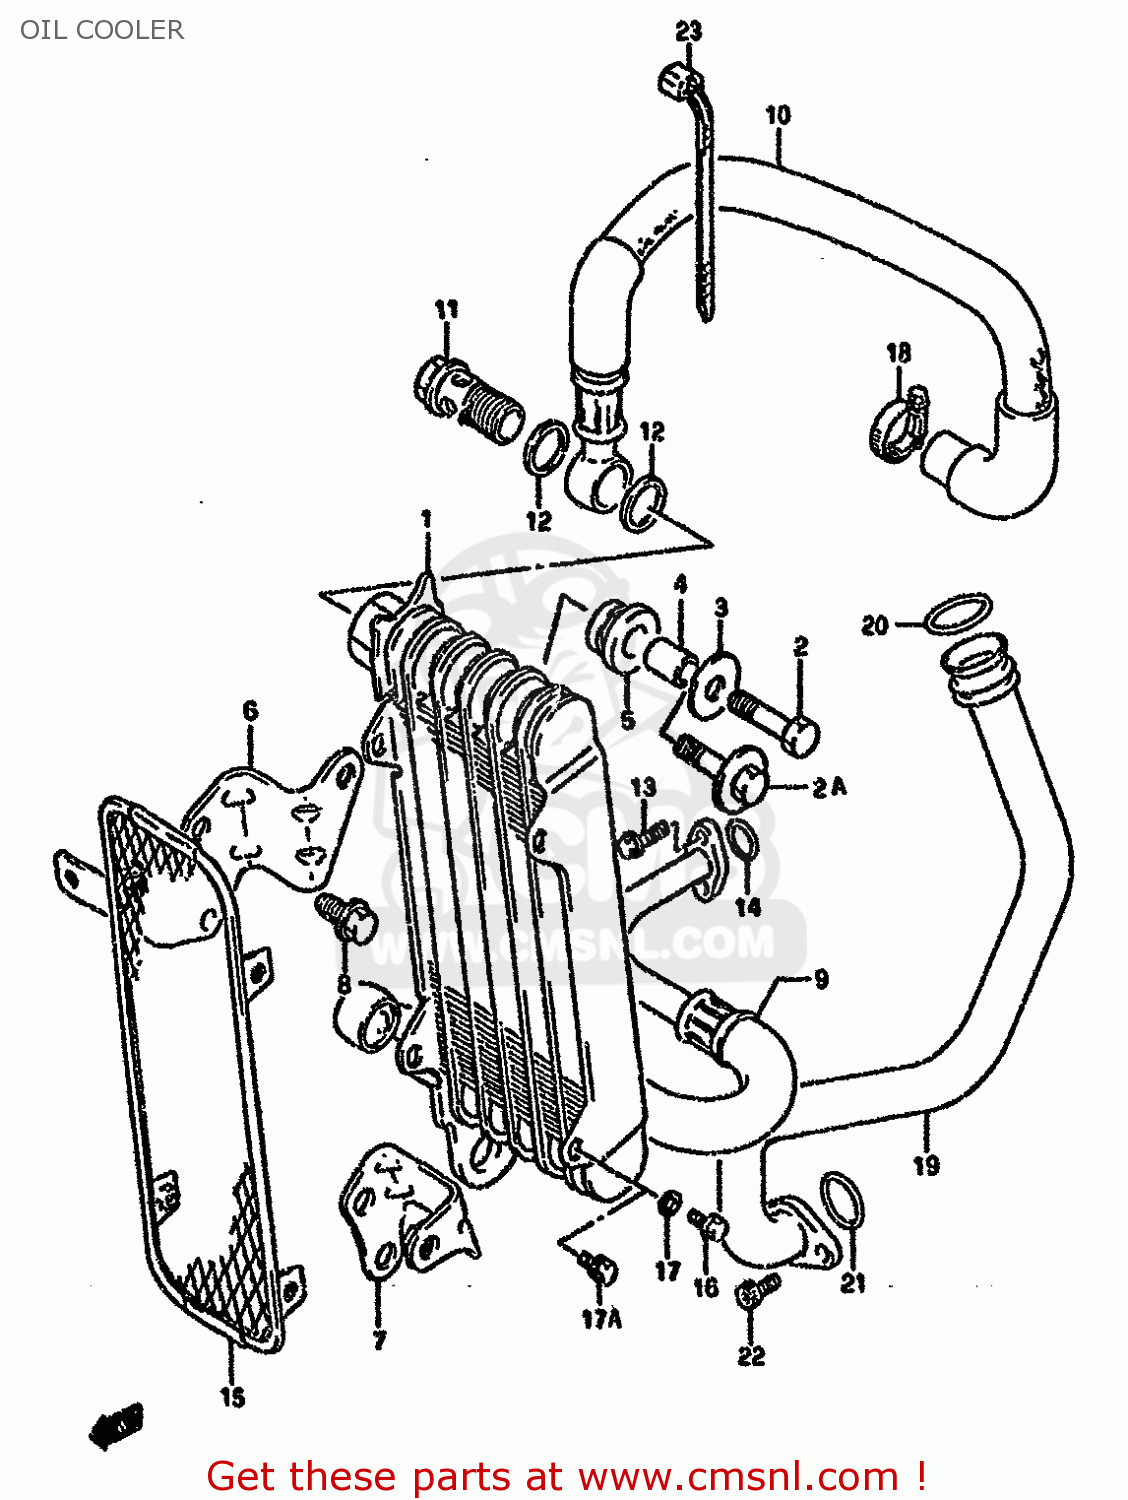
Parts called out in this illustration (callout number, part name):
1	COOLER ASSY,OIL
2	BOLT(8X28)
2A	BOLT 8X28
3	WASHER (8.5X20X1.6)
4	SPACER (8.2X12X17)
5	CUSHION,OIL COOLER
6	BRACKET,OIL COOLER UPR
7	BRACKET,OIL COOLER LWR
8	BOLT
9	HOSE,OIL COOLER NO.1
10	HOSE,OIL COOLER NO.2
11	BOLT UNION
12	GASKET(16X22X2) (NAS)
13	BOLT
14	O RING(D:2.4,ID:12.3)
15	BUMPER,OIL COOLER
16	BOLT
17	WASHER,LOCK
17A	BOLT
18	CLAMP
19	PIPE COMP,OIL RETURN
20	O RING(D:3.7,ID:21.7)
21	O-RING (D:2.4 ID:23.7)
22	BOLT
23	CLAMP L:165
